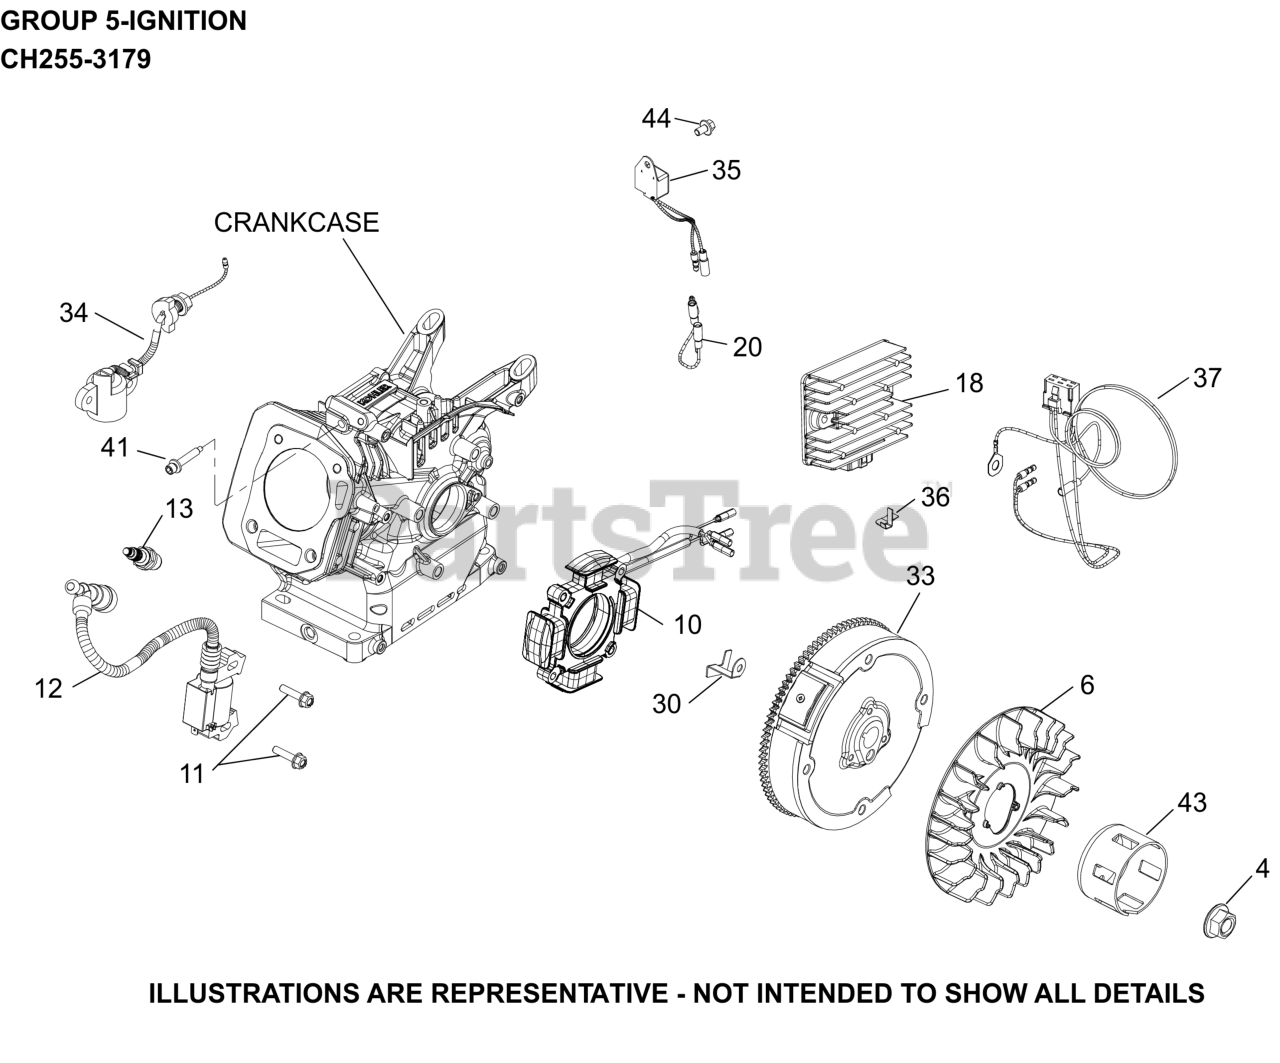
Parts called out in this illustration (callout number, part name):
4	NUT, FLYWHEEL (W/SERRATIONS)
6	FAN, FLYWHEEL
10	STATOR ASSEMBLY, 3 POLE
11	SCREW, M6 X 25-(#25086436S)
12	MODULE, IGNITION
13	PLUG SPARK 12MM RFI
18	REGULATOR, 10 AMP
20	LEAD, OPTIONAL EQUIPMENT
30	BRACKET, FIXED STATOR WIRE
33	FLYWHEEL ASSEMBLY - 10 AMP
34	SWITCH, OIL SENSOR ASSEMBLY
35	CONTROL, OIL ALERT UNIT
36	CLIP, WIRE HARNESS-DISCONTINUED
37	MICROSWITCH WIRING HARNESS
41	SCREW, HEX SOCKET HEAD CAP
43	CUP, STARTER
44	SCREW, FLG M6X1.0X10
